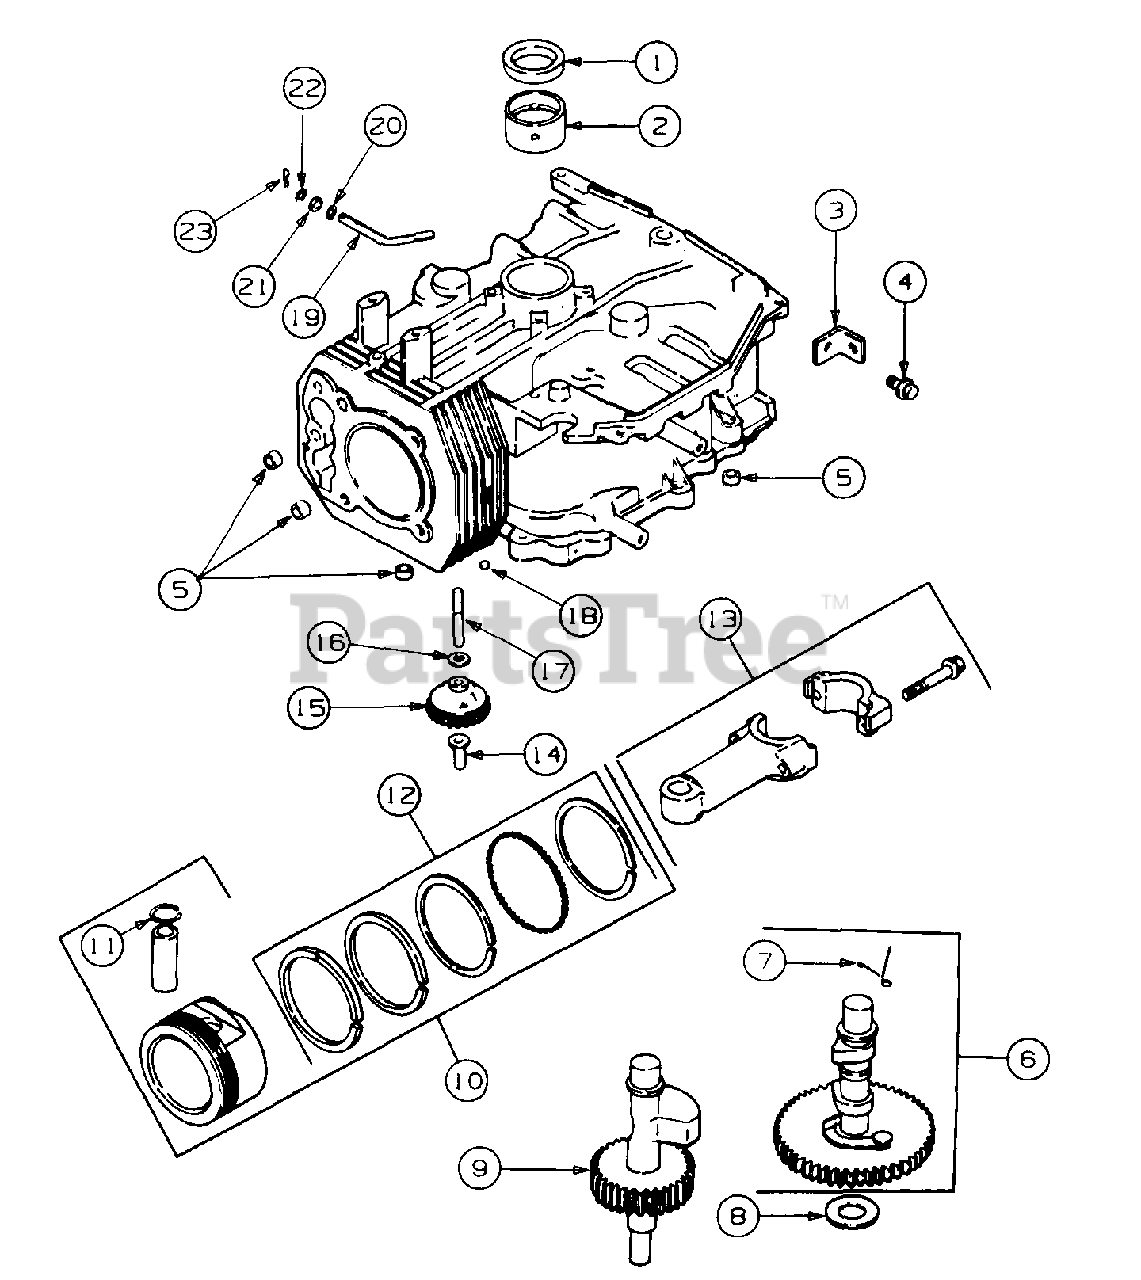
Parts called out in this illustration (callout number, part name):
1	Seal, Crankshaft
2	Bearing, Crankshaft (Std) (Flywheel end)
3	Strap, Lifting
4	Screw, Lifting Strap
5	Dowel, Locating
6	Camshaft Assy (Includes Ref No. 7)
7	Spring, Actuating
8	Shim, Camshaft, .0280
9	Shaft, Balance
10	Piston w/Ring Set (Std)
11	Retainer, Piston Pin
12	Ring Set (Std)
13	Rod, Connecting (Std)
14	Pin, Governor Regulating
15	Gear, Governor Assy
16	Washer, Governor Gear Thrust
17	Shaft, Governor Gear
18	Plug, Cup
19	Shaft, Governor Cross
20	Washer, Plain, 1/4
21	Seal, Governor Cross Shaft
22	Washer, Governor Shaft
23	Pin, Governor Hitch
